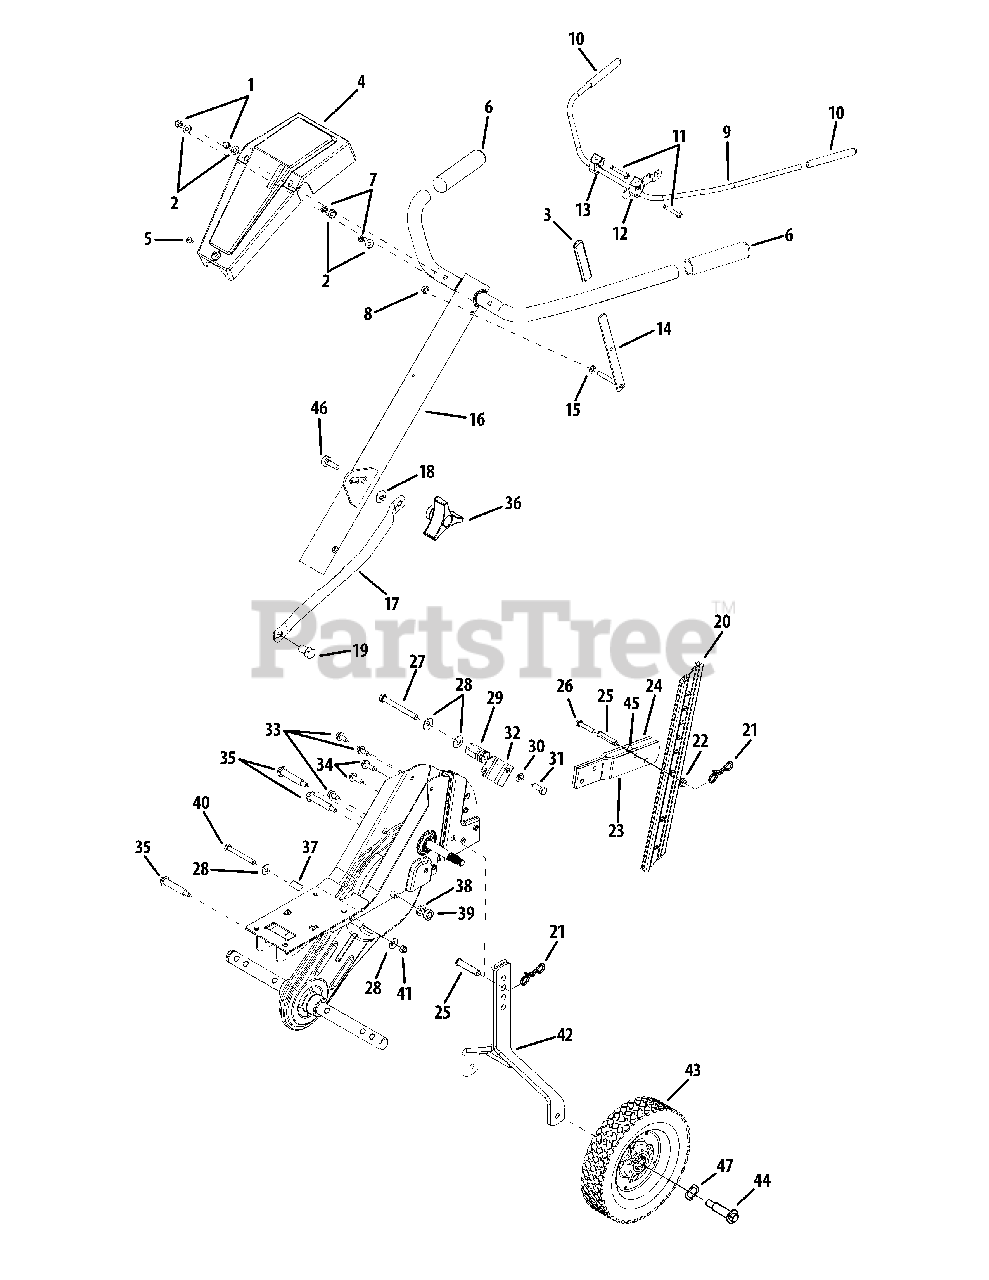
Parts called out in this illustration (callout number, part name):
1	Acorn Lock Nut, 1/4-20
2	Flat Washer, .271" x.630"
3	Reverse Handle Grip
4	Handle Cover w/o throttle
5	Truss Machine Screw, #10 x 1/2"
6	Handle Grip
7	Hex Nut, 1/4-20
8	Cap Speed Nut
9	Clutch Handle Assembly
10	Clutch Grip
11	Hex Bolt, 1/4-20 x 2.25"
12	Clutch Handle Holder
13	Flat Washer, .406 x .875 x .059
14	Reverse Handle Assembly
15	Flat Washer, .344" x .62"
16	Handle Assembly Complete
17	Handle Brace
18	Bell Washer, .34"
19	Hex Bolt, 1/2-20
21	Cotter Pin, Bow Tie
22	Hex Flange L-Nut, 5/16-18
23	Tail Piece Bracket, Left
24	Tail Piece Bracket, Right
25	Clevis Pin
26	Hex Bolt, 5/16-18 x 1.5"
27	Hex Bolt, 5/16-18 x 3"
28	Bell Washer, .340" x .872"
30	L-Washer, 5/16"
31	Hex Bolt, 5/16-18
32	Cable Guide Bracket
33	Screw, :5/16-18 x 0.75
34	Hex Washer TT-Tap Screw
35	Shoulder Bolt, 5/16-18
36	Hand Knob
38	Lock Washer, 7/16
39	Jam Nut, 7/16-20
40	Hex Cap Screw, 5/16-18 x 3
41	Nylon Hex Nut, 5/16-18
42	Wheel Hanger Bracket Assembly
43	Wheel, 8 x 1.75
44	Shoulder Screw, .496 x 1.445
46	Carriage Bolt, 5/16-18 x 1
47	Wave Washer .531 x .781 x .013
